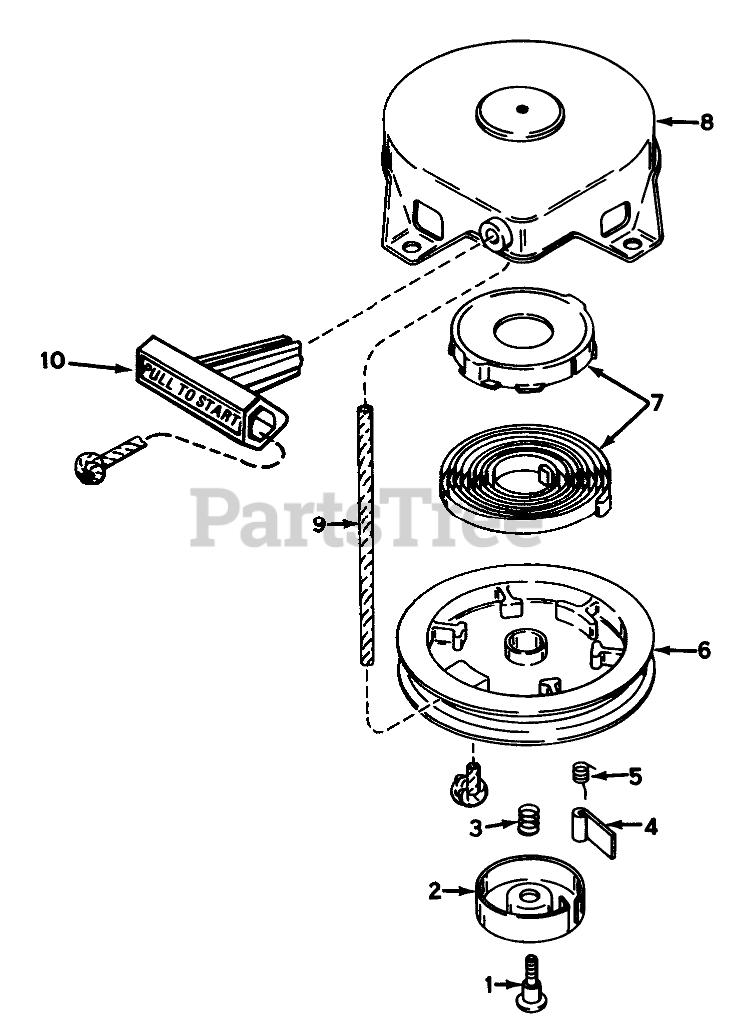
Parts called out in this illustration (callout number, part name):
2	Retainer
3	Spring-Brake
4	Dog-Starter
5	Spring-Dog
7	Spring & Keeper Assy
8	Housing-Starter
9	Rope-Starter (98 cut to length)
10	Handle-Starter
